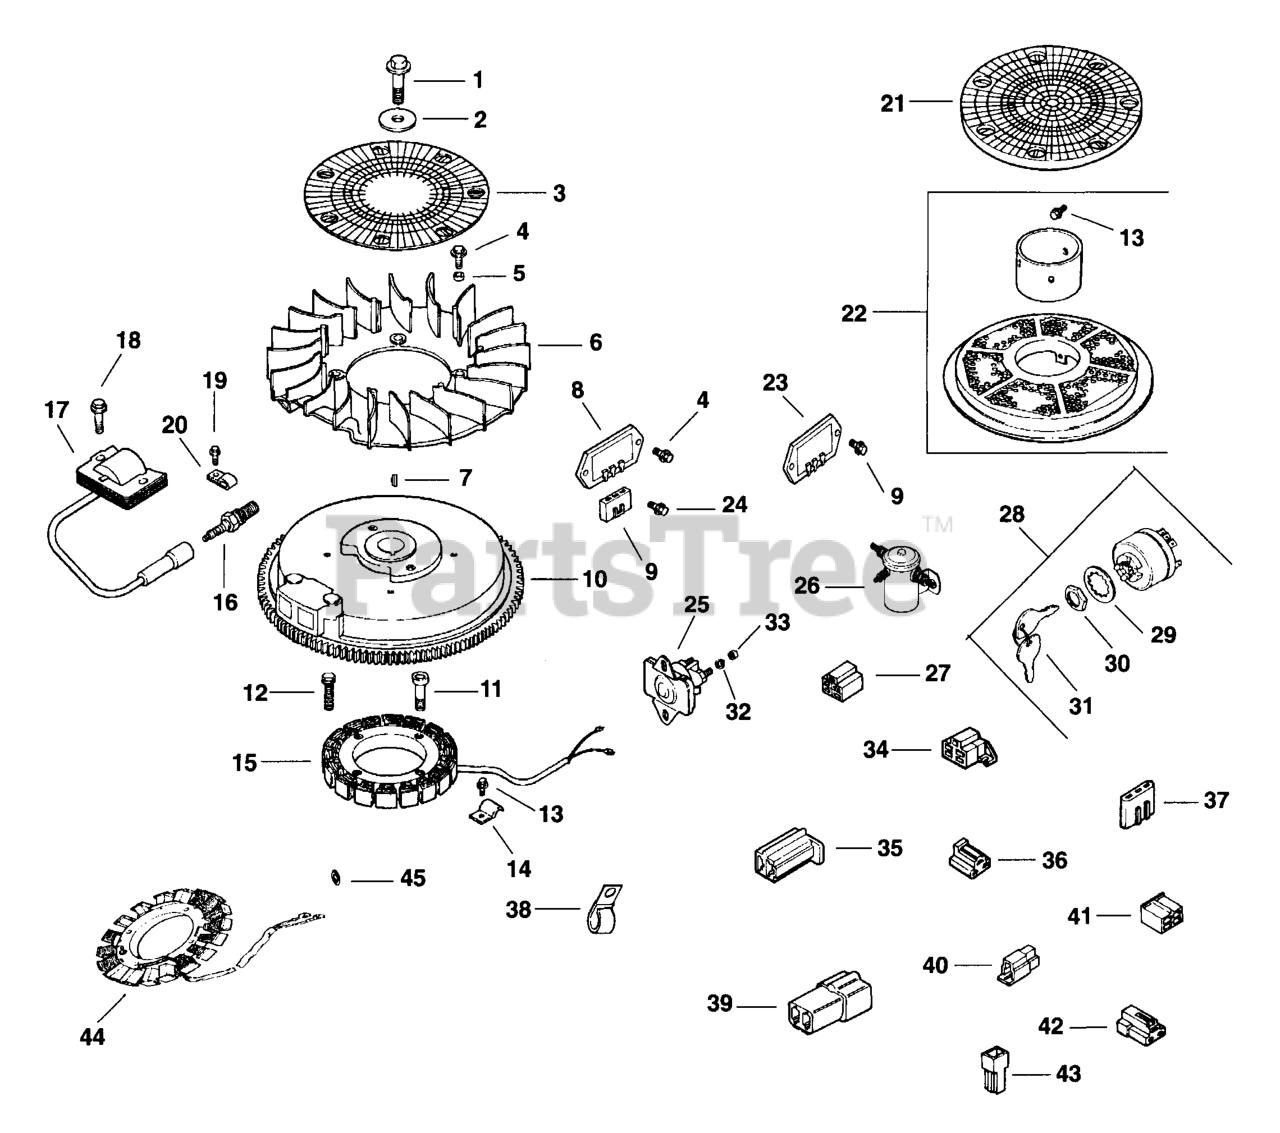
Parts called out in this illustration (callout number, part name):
1	SCREW, FLG M10X1.5X45 - (#25086361S)
2	WASHER, FLAT 13/32"
4	SCREW - USE M-639016
5	BOLT - USE 25 086 47
6	FAN - USE 12 157 03
7	KEY, 3/16" X 5/8"
8	REG/RECT-15 AMP (KM)-USE 41 403 10-S
9	CONNECTOR, BODY (KM)-USE 25 155 41-S
10	FLYWHEEL - USE 12 025 15
11	SCREW - USE M-548025
13	SCREW - USE M-545010
14	CLIP - USE X-728-1
15	STATOR - USE 24 085 01
16	PLUG, SPARK (STD)
17	MODULE - USE 12 584 04
18	Screw, hex. flange M5x0.8x20
21	SCREEN, GRASS
